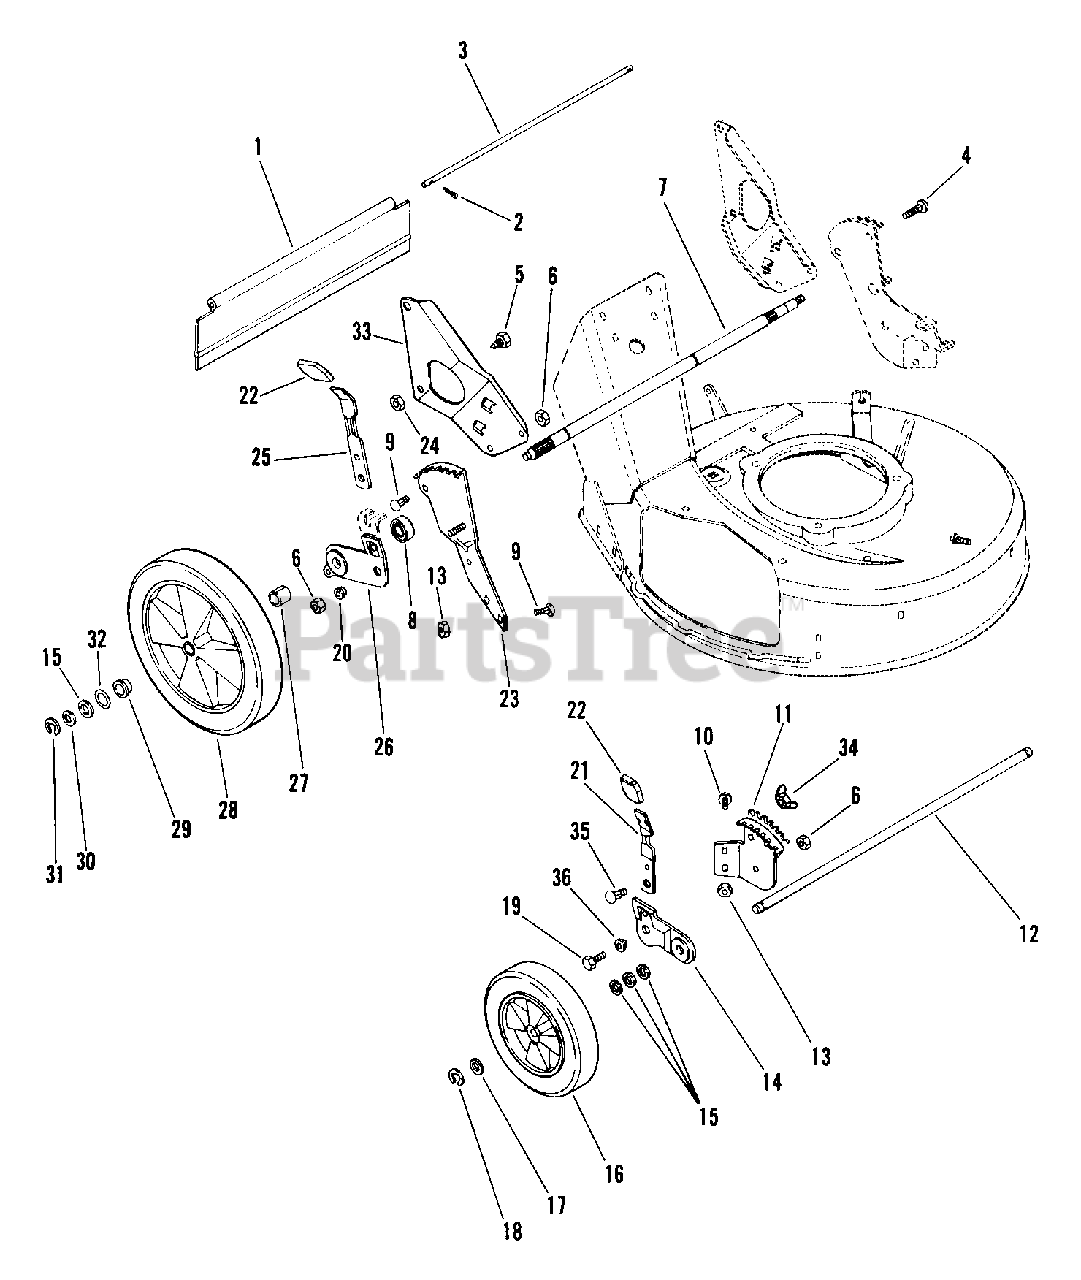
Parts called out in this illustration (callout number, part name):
1	REAR PROTECTIVE GUARD, PUSH
1	REAR PROTECTIVE GUARD, S.P.
2	PIN-COTR .06X.50
3	ROD
4	BLT-RDHDSQNK .31-18X1.0 SHT PL
4	BLT-RDHDSQNK .31-18X1.25 SHTPL
5	HANDLEBAR STUD
5	BLT-HEX .31-18X.75 PL GR5
6	NUT-LK .312-18 GR A PL
7	REAR AXLE,5/8 DIA
7	REAR AXLE - PUSH MOWER
8	BRG-BALL .625X1.383X.50
9	BLT-RDHDSQNK .312-18X.62SHTPL
10	BLT-RDHDSQSHNK .31-18X.50 YZ
11	FRONT QUADRANT, L.H.
11	L.H. FRONT QUADRANT
11	FRONT QUADRANT, R.H.
11	R.H. FRONT QUADRANT
12	FRONT AXLE
13	NUT-FLG. .312-18 PL
14	LEFT ADJUSTOR BRACKET ASSEMBLY
14	L.H. FRONT ADV. BRACKET ASSEM.
14	RIGHT ADJUSTOR BRACKET ASSEMBL
14	R.H. FRONT ADV. BRACKET ASSEM.
15	WSHR-FL-STL .520X.827X.062 YZ
16	WHEEL
17	WSHR-FL-STL .505X.880X.072 PL
18	RG-RTNG-EXT .438X.035
19	BLT-HEX .31-18X.88 PL GR2
20	BSHG-FLG .32X.500X.344X.880
21	FRONT HEIGHT ADJUSTMENT LEVER
23	QUADRANT, REAR - L.H.
23	REAR QUADRANT, R.H.
24	NUT-LK-JAM-CTR .375-16 PL
25	HEIGHT ADJUSTMENT LEVER
26	REAR BRACKET & BEARING ASSEMBL
26	REAR BRACKET & BEARING ASSY RH
26	R.H. REAR ADJUSTOR BRACKET
26	REAR ADJUSTMENT BRACKET L.H.
26	L.H. REAR ADJUSTOR BRACKET
27	SPACER TUBE,PUSH LH
27	SPACER TUBE PUSH RH
27	SPACER TUBE, SELF PROPEL
28	WHEEL
28	LH WHEEL
28	RH WHEEL
28	10 1/2 TIRE SKIN
29	BSHG-SLV .625X.750X.500
30	WSHR-FL-STL .630X1.005X.062 PL
31	RG-RTNG-EXT .500X.042 (E)
32	SEAL .625X.875X.125
33	RH HANDLEBAR MTG. BRKT.
33	LH HANDLEBAR MTG. BRKT.
34	NUT-LK WING .250-20
35	BLT-RDHDSQNK .25-20X.75
36	BSHG-FLG .32X.500X.344X.880
36	BSHG, FLG .325X.499X.26X.88
